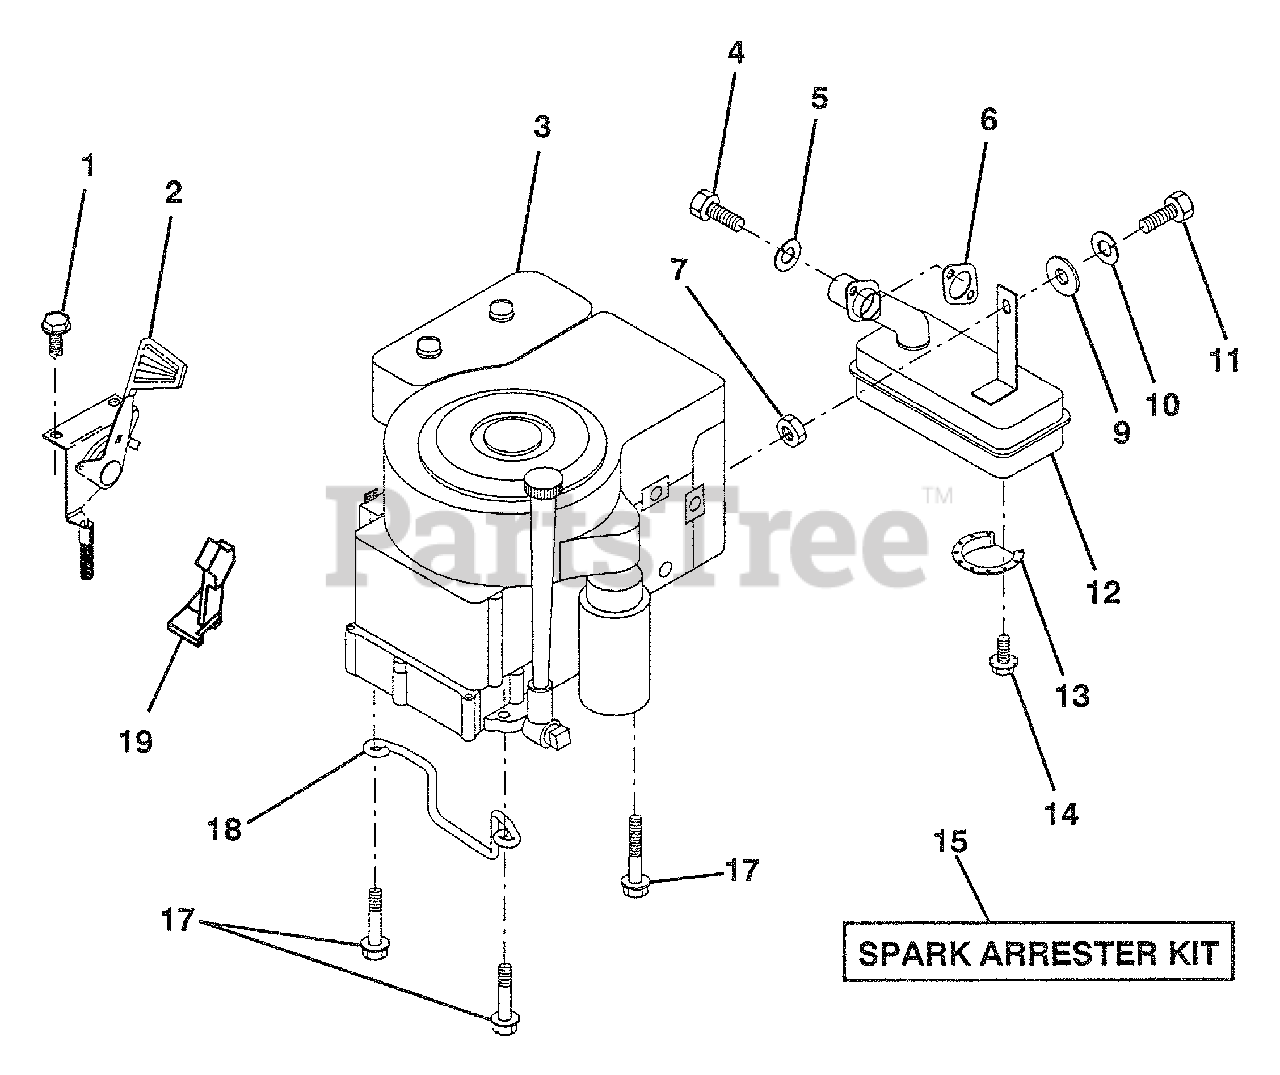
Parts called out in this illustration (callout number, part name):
1	Screw, Hex Thd. Cut 1/4-20 x 1/2
2	Control, Throttle
4	Screw, Hex, Cap 5/16-18 x 3/4
5	Washer, Lock Heavy Helical Spring 5/16
6	Gasket, Exhaust
7	Nut Fin Hex 5/16-18
9	Washer 5/16 x 3/4 x 16
10	Washer, Lock Heavy Helical Spring 1/4
11	Bolt, Hex Fin. 1/4-20 UNC x 1
12	Muffler
13	Deflector, Muffler
14	Screw, Spiderlock Hex Hd. 8 x 1/2 ABTPS
15	Arrester, Spark
17	Screw, Hex Washer Head, Thdrol. 3/8-16 x 1-1/2
18	Keeper, Ground Drive Belt
19	Stop, Throttle
